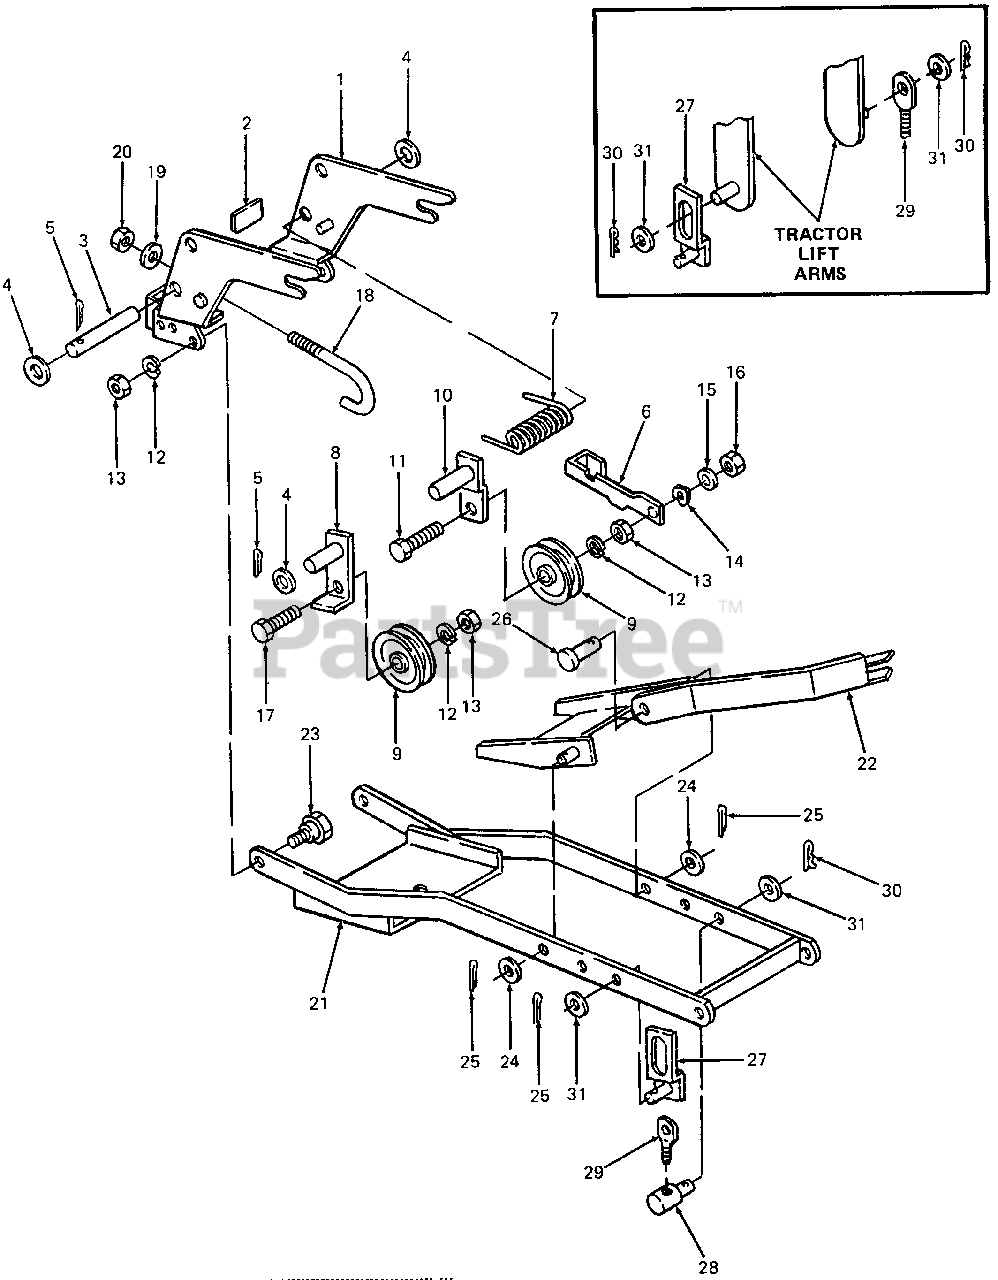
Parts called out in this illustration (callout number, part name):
1	Hanger Assy, Front
2	Graphic, Idler Adjustment
3	Shaft, Idler Pivot
4	Washer, Flat, .640 X .943 X .050
5	Pin, Cotter, 1/8 Dia X 1.0
7	Spring, Idler Torsion
8	Arm Assy, Idler - LH
9	Pulley, Idler
10	Arm Assy, Idler - RH
11	Screw, Hex Cap, 3/8-16 X 2.25 Lg GR5
12	Washer, Lock, 3/8
13	Nut, Hex, 3/8-16 GR5
14	Washer, Wave, .406 X .64 X .015
15	Washer, Flat, .405 X .75 X .06
16	Nut, Hex Center Lock, 3/8-16 GR5
17	Screw, Hex Cap, 3/8-16 X 1.5 Lg GR5
18	Bolt, Idler Adjuster
19	Washer, Flat, .34 X .68 X .062
20	Nut, Hex Center Lock, 5/16-18 GR5
23	Bolt, Shoulder
24	Washer, Flat, .531 X 1.0 X .027 Thk
25	Pin, Cotter, 3/16 Dia X 1.0 Lg
26	Pin, Clevis, .50 Dia X 2.25 Lg
27	See 360 Mower Adapter
28	Ferrule, Adjustment
29	See 360 Mower Adapter
30	Pin, Internal Cotter
